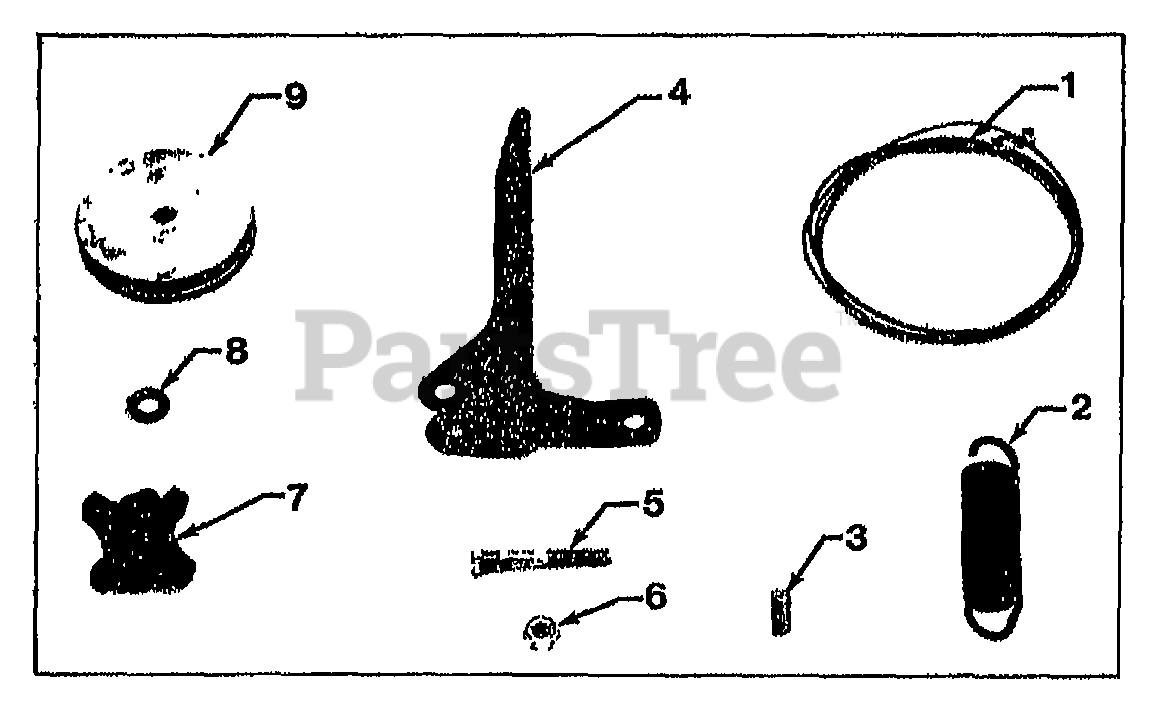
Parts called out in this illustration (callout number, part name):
2	SPRING .75 X 3
3	PLUG-CAP .25X.44 RED
4	HANDLE-ZINC PLATED
5	SCR-HH 1/4-20X1.75 G5
6	NUT-LK 1/4-20
8	WASHER-LK .312
9	WHEEL-CABLE ADJUST
